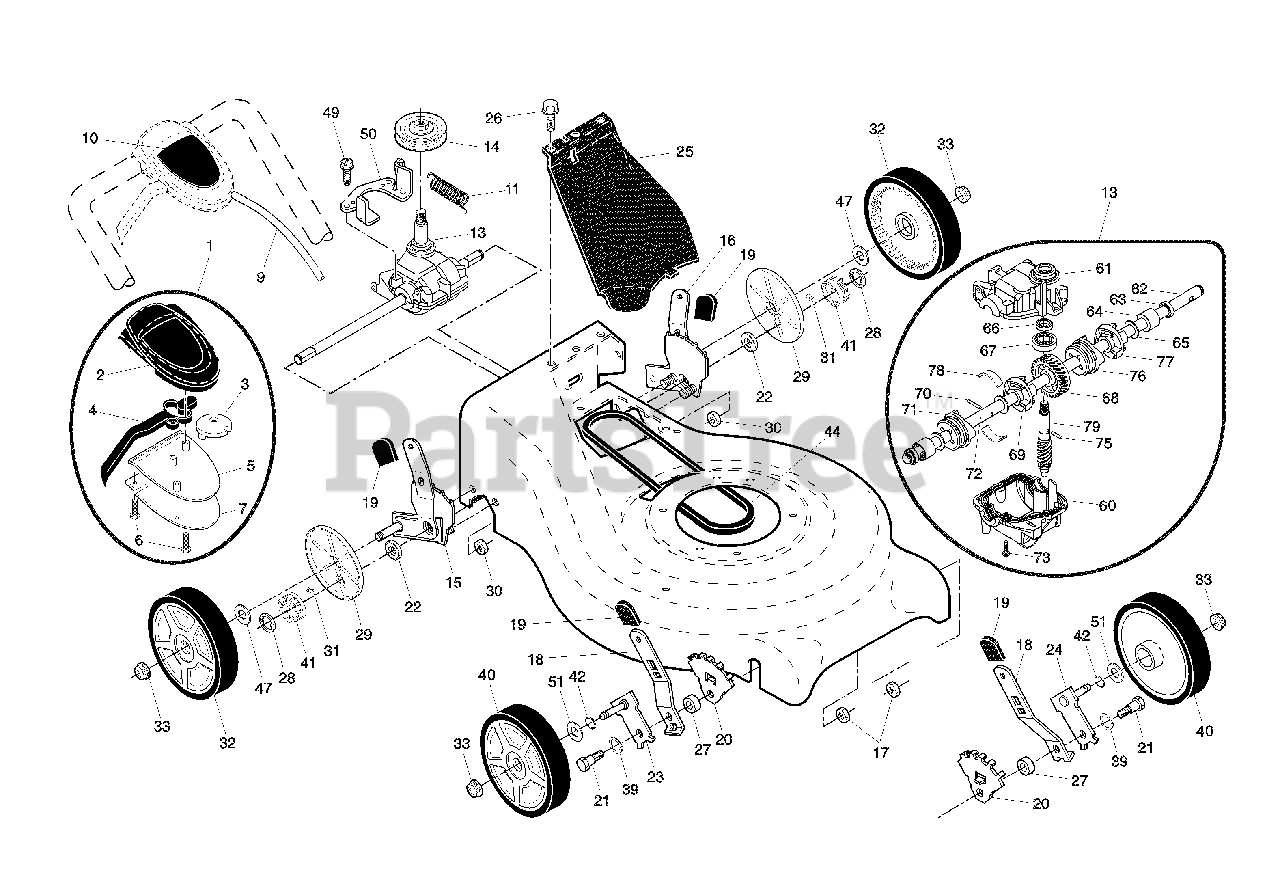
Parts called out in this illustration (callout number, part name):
1	Drive Control Assembly
2	Cover, Top, Drive Control
4	Lever, Drive Control
5	Cover, Bottom, Drive Control
6	Screw, Phillips Head #10 x 5/8
7	Mounting Bracket, Drive Control
9	Cable, Drive Control
10	Decal, Drive Control
13	Gear Case Assembly, Complete
14	Pulley, Drive
15	Kit, Wheel Adjuster Assembly, RH
16	Kit, Wheel Adjuster Assembly, LH
17	Nut, Hex
18	Spring Selector
19	Knob, Selector Spring
20	Bracket, Wheel Adjusting
21	Bolt, Shoulder, Hex Head
22	Bearing, Ball
23	Axle Arm Assembly, RH
24	Axle Arm Assembly, LH
25	Cover Drive
26	Screw, Threaded, Rolled #10-25 x 1/2
28	E-Ring 7/16
29	Cover, Dust, Wheel
30	Nut, Hex
32	Wheel & Tire Assembly, Rear
33	Nut, Hex, Flangelock 3/8-16
39	Washer, Curved, Cylindrical
40	Wheel & Tire Assembly, Front 8 x 2
47	Washer 1/2 x 1-1/2 x .134
49	Screw, Hi-Lo Thread #12 x 5/8
50	Belt Keeper
51	Washer, Flat 1/2
60	Case, Lower
61	Case, Upper
62	Shaft, Output, Long
63	Seal, Output Shaft
66	Seal, Worm Shaft
67	Bearing, Ball
68	Gear, 28 Teeth
69	Fixed Dog Clutch, LH
70	Pin, Output Shaft
71	Movable Dog Clutch, LH
72	Shaft, Output, Short
73	Screw, Case
75	Pin, Worm Shaft
76	Fixed Dog Clutch, RH
77	Movable Dog Clutch, RH
78	Spring, Leaf
79	Shaft, Worm
